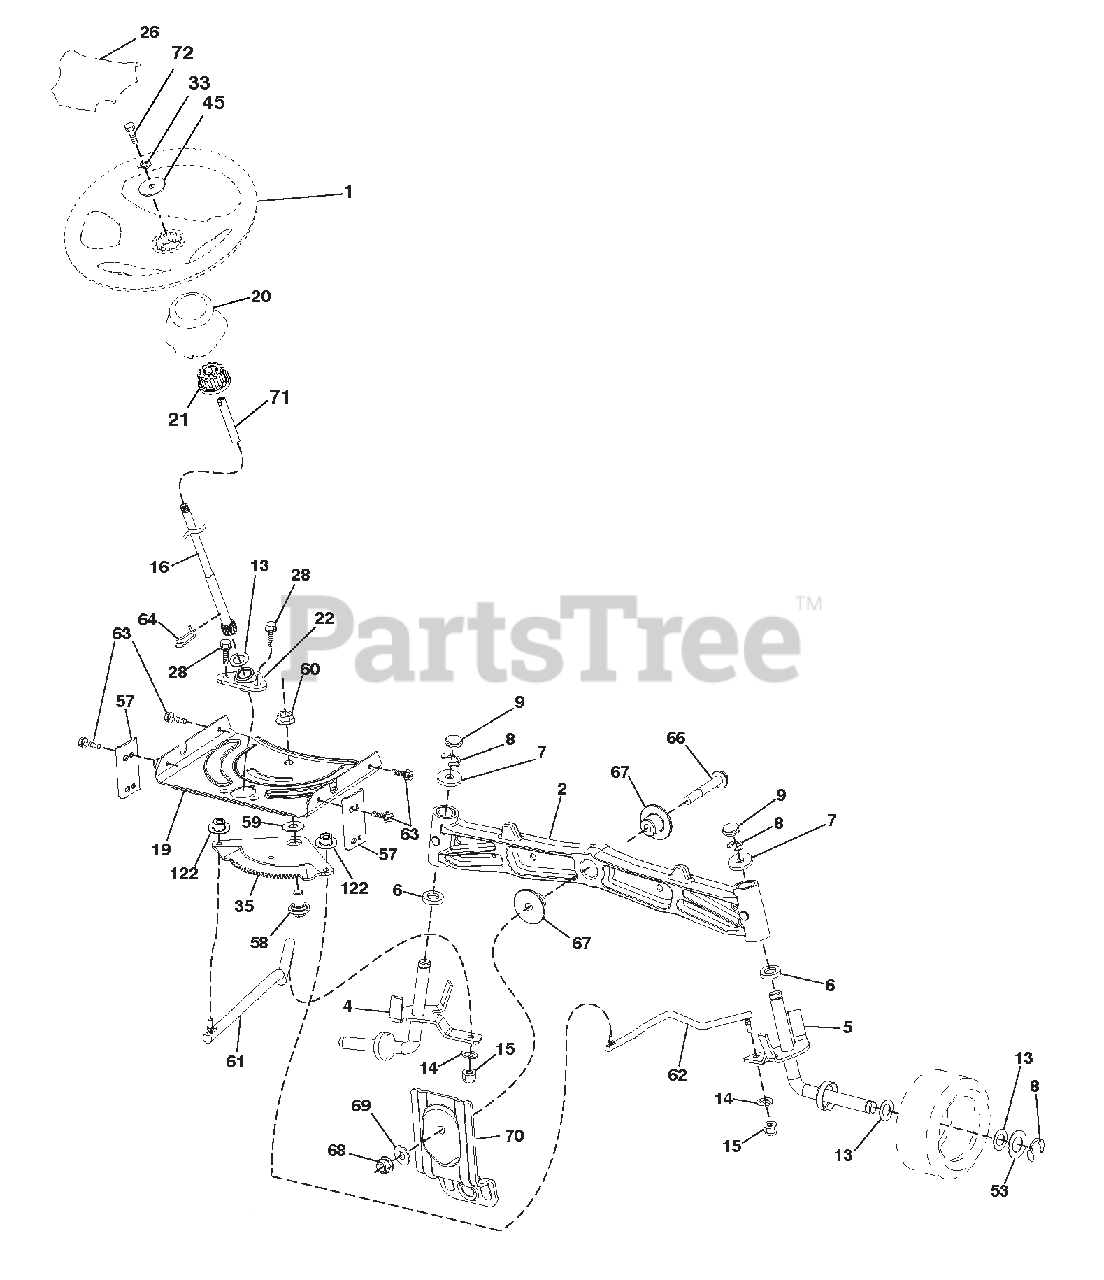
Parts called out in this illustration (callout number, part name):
1	WHEEL.STEERING.HARD RIM.BLACK
2	AXLE.CAST IRON
4	SPINDLE.WELDED.LH.15"TEX
5	SPINDLE.WELDED.RH.15"TEX
6	WAHSER THRUST .75 X 1.230
7	WASHER.25/32 X 1-5/8 X 16GA.
8	RING.KLIP.#T5304-75
9	CAP.SPINDLE.FR.TOP.BLK.
13	WASHER.25/32 X 1 1/4 X 16 GA.
14	Washer, Lock 3/8
15	NUT.CROWNLOCK.3/8-24
16	SHAFT.STEER.3/4 TEX.NON-PLATED
19	PLATE.STEER.DDL.NLT/NGT
20	BOOT.STEERING
21	ADAPTER.WHEEL.STRG..760
22	STEERING SUPT. LOWER
26	CAP WHEEL STEERING HRS/SRS BLK
28	SCREW.HEXWSH THDR3/8-16X3/4.BL
33	Washer, Lock 5/16
35	GEAR SECTOR.PLATE.DDL.NLT/NGT
45	WASHER.11/32ID X2 3/8OD X 12GA
53	WASHER.HARDEN..793 X 1.637X060
57	BRACKET.UPSTOP.TEX
58	BOLT.SHOULDER.SECTOR.PIVOT.CFM
59	WASHER.THRUST.SECTOR.STEER.NLT
60	NUT.FLANGE LOCK.5/8-11
61	DRAGLINK.LH.BALLSTUD.DDL.
62	DRAGLINK.RH.BALLSTUD.DDL
63	SCREW.5/16-18X3/4.SMGML.TAP/BL
64	RETAINER.CLIP.SPRING.STEERING
66	BOLT.HEX.FGHD.7/16-14 X 3.SERR
67	BUSHING.PM.FRONT AXLE
68	NUT.LOCK.FLANGE.7/16-14.GR5
69	WASHER.1.5 X .505 X .118
70	BRACKET.DECK.SUSPENSION.FRONT
71	Extension Steering
72	Bolt 5/16-18 x 14 w/Patch
122	CAP GEAR SECTOR
